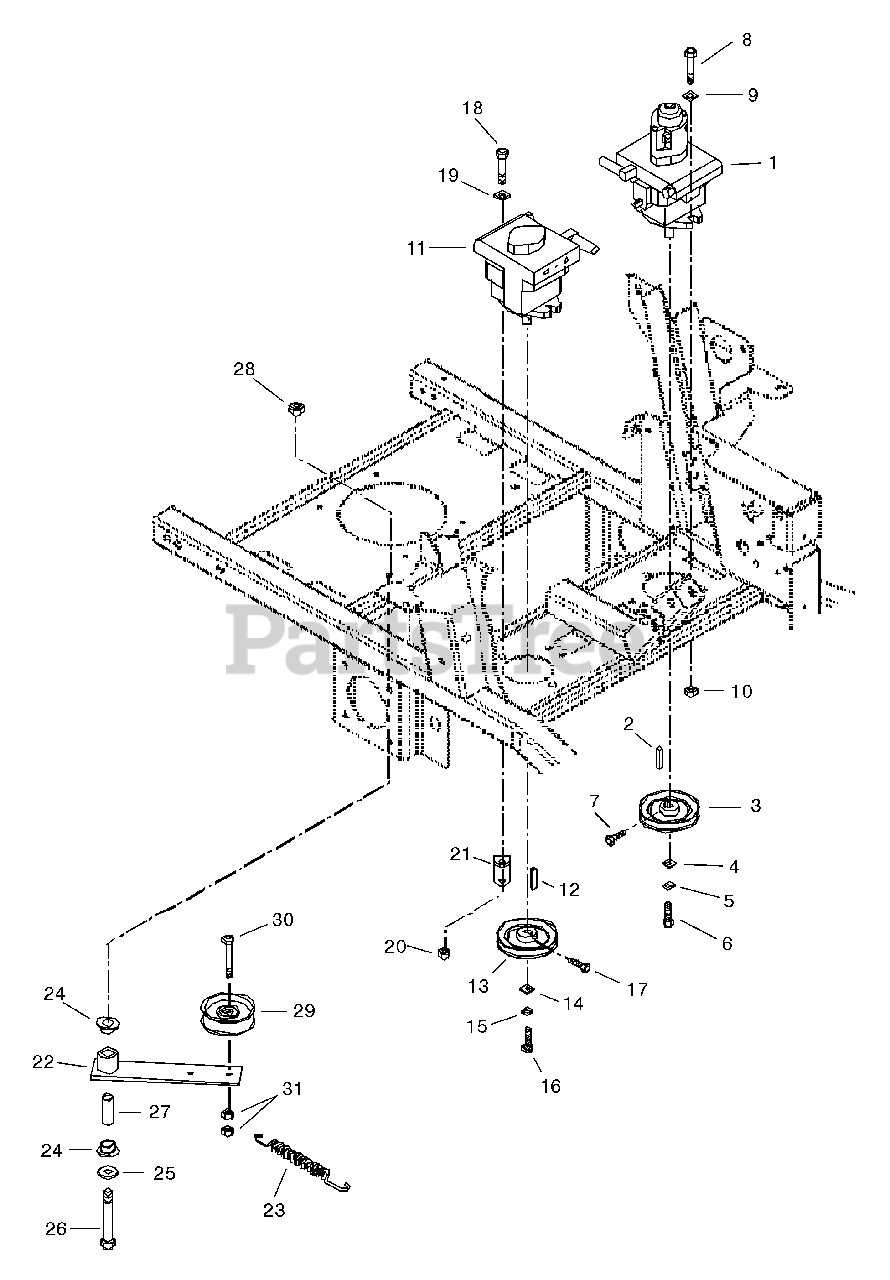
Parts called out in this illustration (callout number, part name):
1	Hydrostat BDP with Auxiliary
2	Key-Straight 5mm x 25mm x 5mm
3	Sheave 4.0 x .199
4	Washer-Flat-Steel .25 x 1.0 x .048
5	Washer-Locking .25 x .062
6	Bolt-Hex M6 x 1.0 x 12
7	Bolt-Hex .25-20 x .50 Grade 5
8	Bolt-Hex .38-16 x 1.25 Grade 5
9	Washer-Flat-Steel .390 x .75 x .125
10	Nut-Locking-Center .38-16
11	Variable-Displace Pump
12	Key-Straight 5mm x 25mm x 5mm
13	Sheave 4.0 x .199
14	Washer-Flat-Steel .25 x 1.0 x .048
15	Washer-Locking .25 x .062
16	Bolt-Hex M6 x 1.0 x 12
17	Bolt-Hex .25-20 x .50 Grade 5
18	Bolt-Hex .38-16 x 1.25 Grade 5
19	Washer-Flat-Steel .390 x .75 x .125
20	Nut-Locking-Center .38-16
21	Anchor-Spring-Idler
22	Weldment-Ground Drive Idler
23	Spring-Tension .120 x .845 x 6.500
24	Bushing-Flange .762 x 1.0 x .580 x 1.48
25	Washer-Flat-Steel .531 x 1.06 x .095
26	Bolt-Hex .50-13 x 3.00 Grade 5
27	Bushing-Steel .560 x .745 x 2.04
28	Nut-Locking-Center .50-13
29	Assembly-Idler Pulley
30	Bolt-Hex .38-16 x 2.00 Grade 5
31	Nut-Locking-Center .38-16
